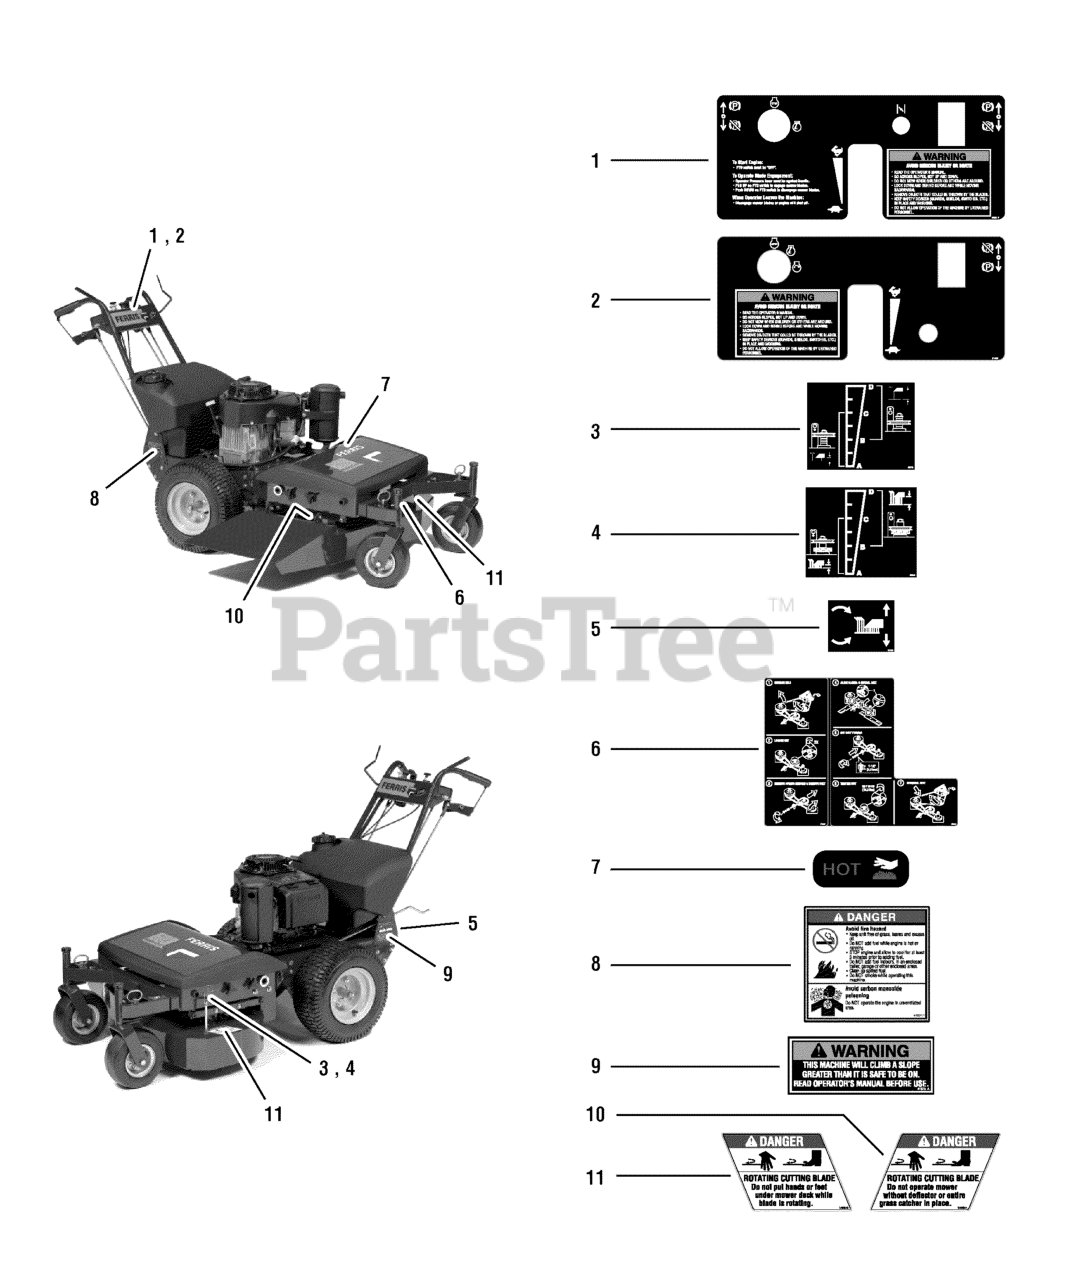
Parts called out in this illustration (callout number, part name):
1	DECAL, Control Panel
2	DECAL, Control Panel
3	DECAL, Height Of Cut
4	DECAL, Height Of Cut
5	DECAL, Cut Height Adjust
6	DECAL, Belt R&R
7	DECAL, Hot Surface
8	DECAL, Danger
9	DECAL, Warning, Machine Will Climb
10	DECAL, Danger (Chute In Place)
11	DECAL, Danger (Hand Under Deck)
